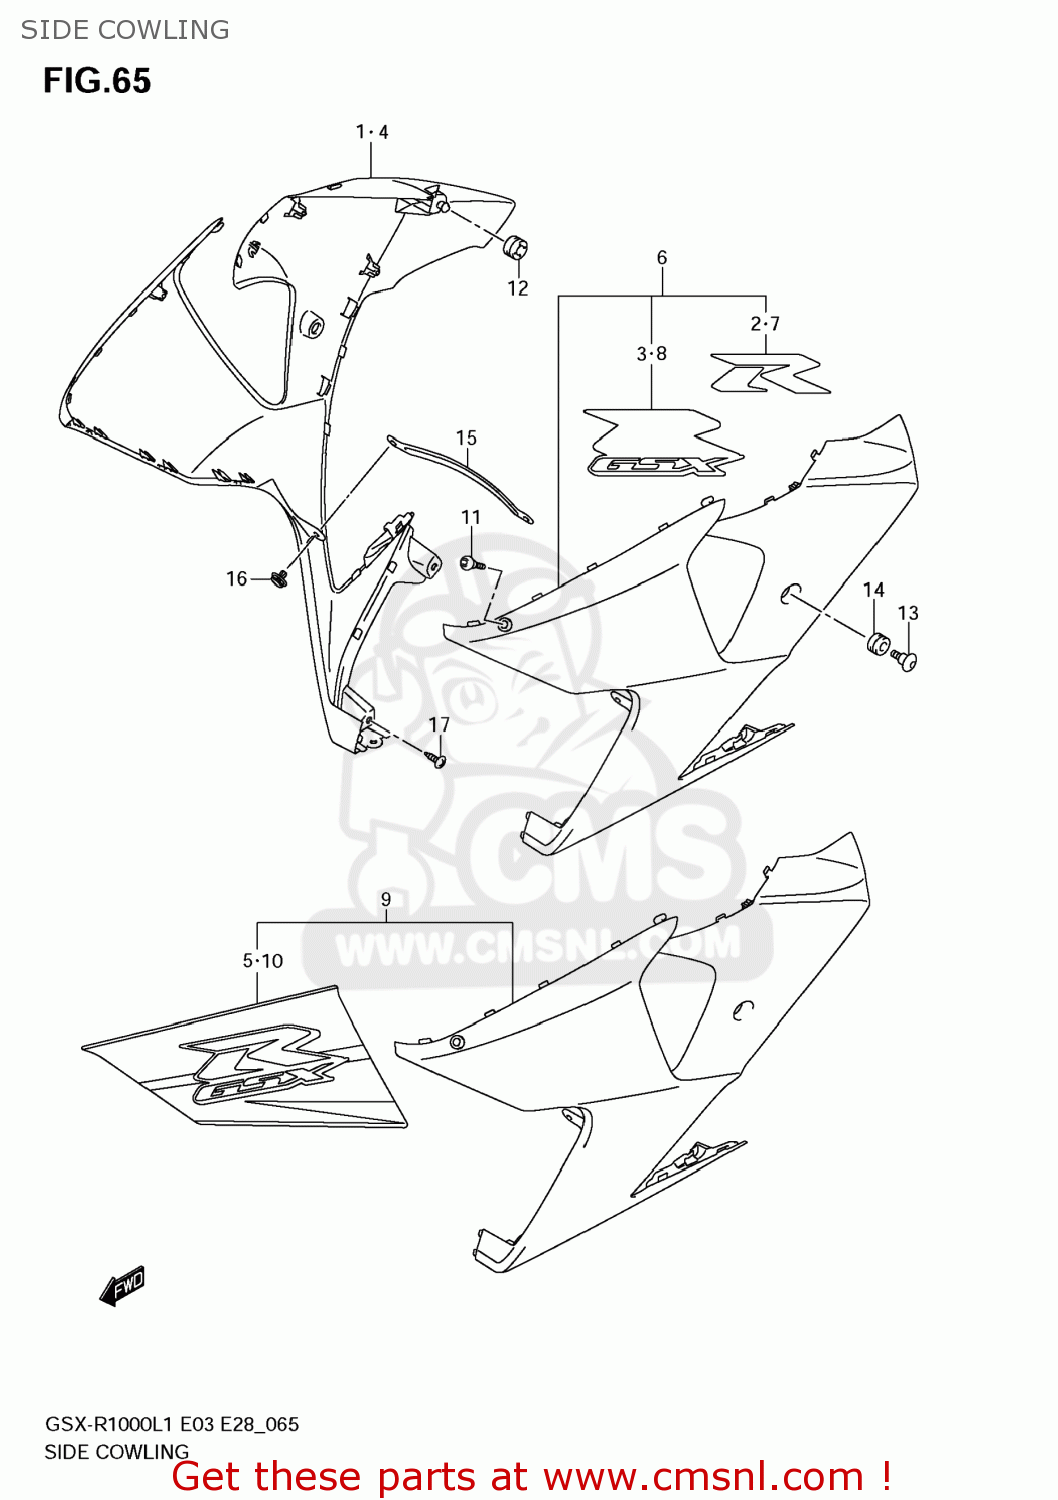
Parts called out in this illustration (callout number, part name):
1	COWLING,SIDE,R(BLACK)
2	EMBLEM,R
3	EMBLEM,GSXR,R
4	COWLING,SIDE,R(WHITE)
5	TAPE,SIDE COWLING,R
6	COWLING,SIDE,L(BLACK)
7	EMBLEM,R
8	EMBLEM,GSXR,L
9	COWLING,SIDE,L(WHITE)
10	TAPE,SIDE COWLING,L
11	SCREW(5X16)
12	CUSHION
13	SCREW(6X20)
14	CUSHION
15	BRACKET,UNDER COWLING CTR
16	CLIP
17	SCREW
